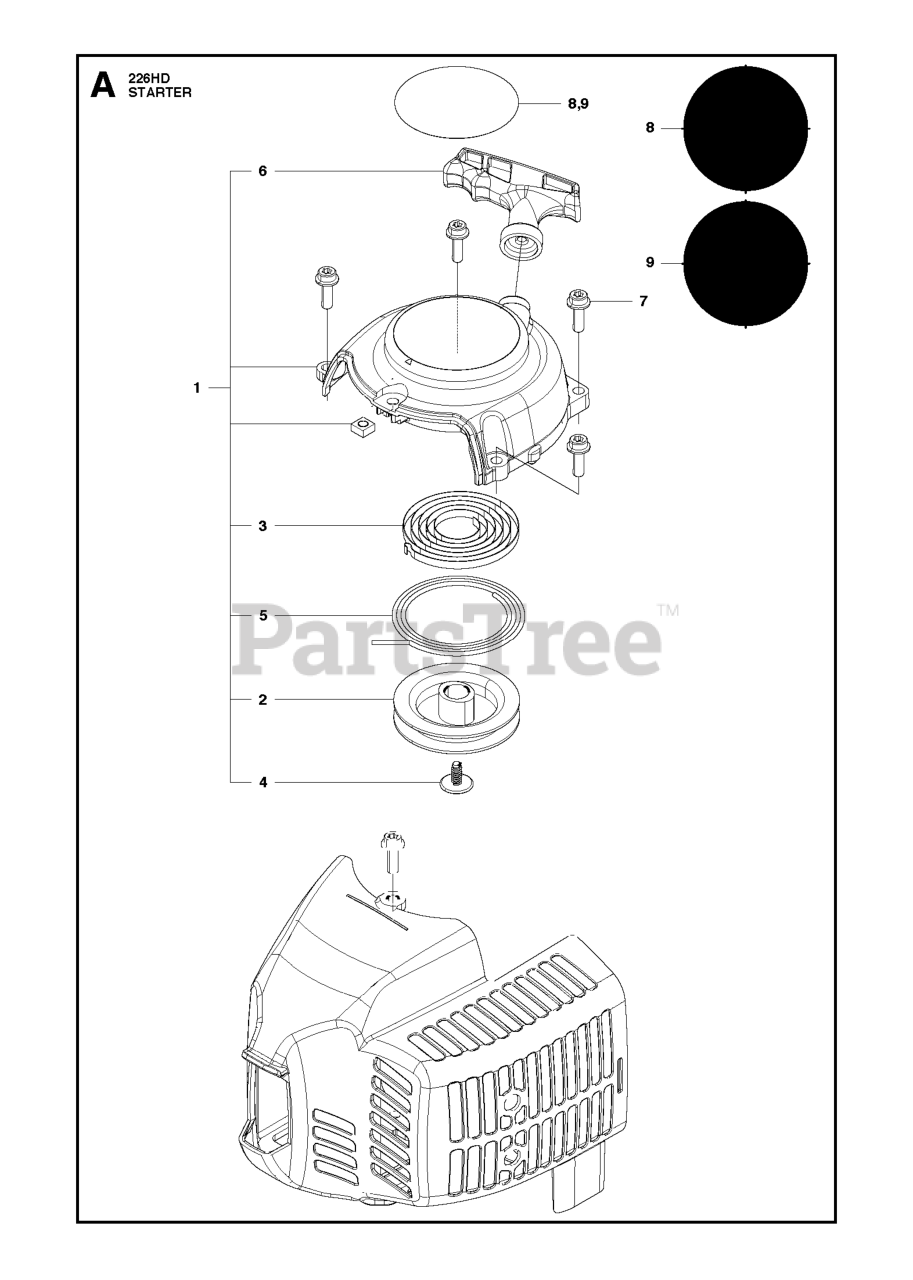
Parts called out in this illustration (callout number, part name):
1	RECOIL ASSY
4	SCREW
8	LABEL, RECOIL
